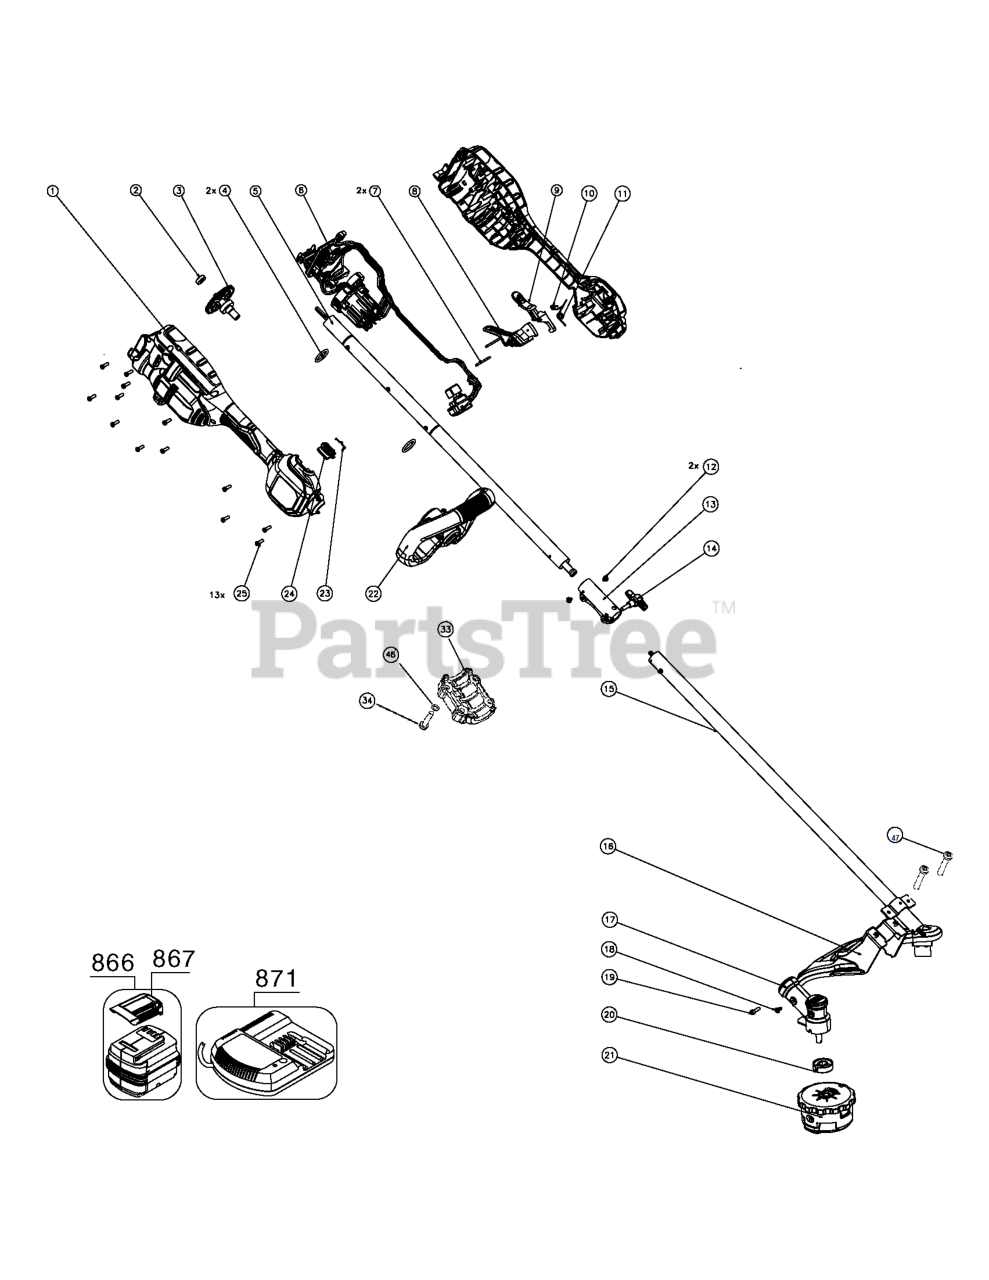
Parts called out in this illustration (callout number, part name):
1	HOUSING ASM DCST472
2	BEARING
3	GEAR ASM:OUTPUT:W/SHF
4	RUBBER
5	POLE PIECE
6	MOTOR SA
7	PIN
8	SELF RESET TRIGGER
9	ACTUATOR
10	SPRING
11	SPRING
12	SCREW
13	COUPLING
14	KNOB COUPLING
15	POLE PIECE
16	GUARD
16	GUARD SA
17	GEARCASE
18	SCREW
19	SCREW
20	PLATE
21	HEAD ASM
22	HANDLE AUX DEWALT
22	HANDLE W/BARRIER
23	DETENT SPRING
24	ACTUATOR
25	SCREW M4.55X16 T20-PLAS THD FRM
33	CLAMP
34	HANDLE BOLT
46	WASHER
47	SCREW
866	60V BATT FLEXVOLT 3AH/9AH DCB609
867	BATTERY CAP
871	CHARGER
